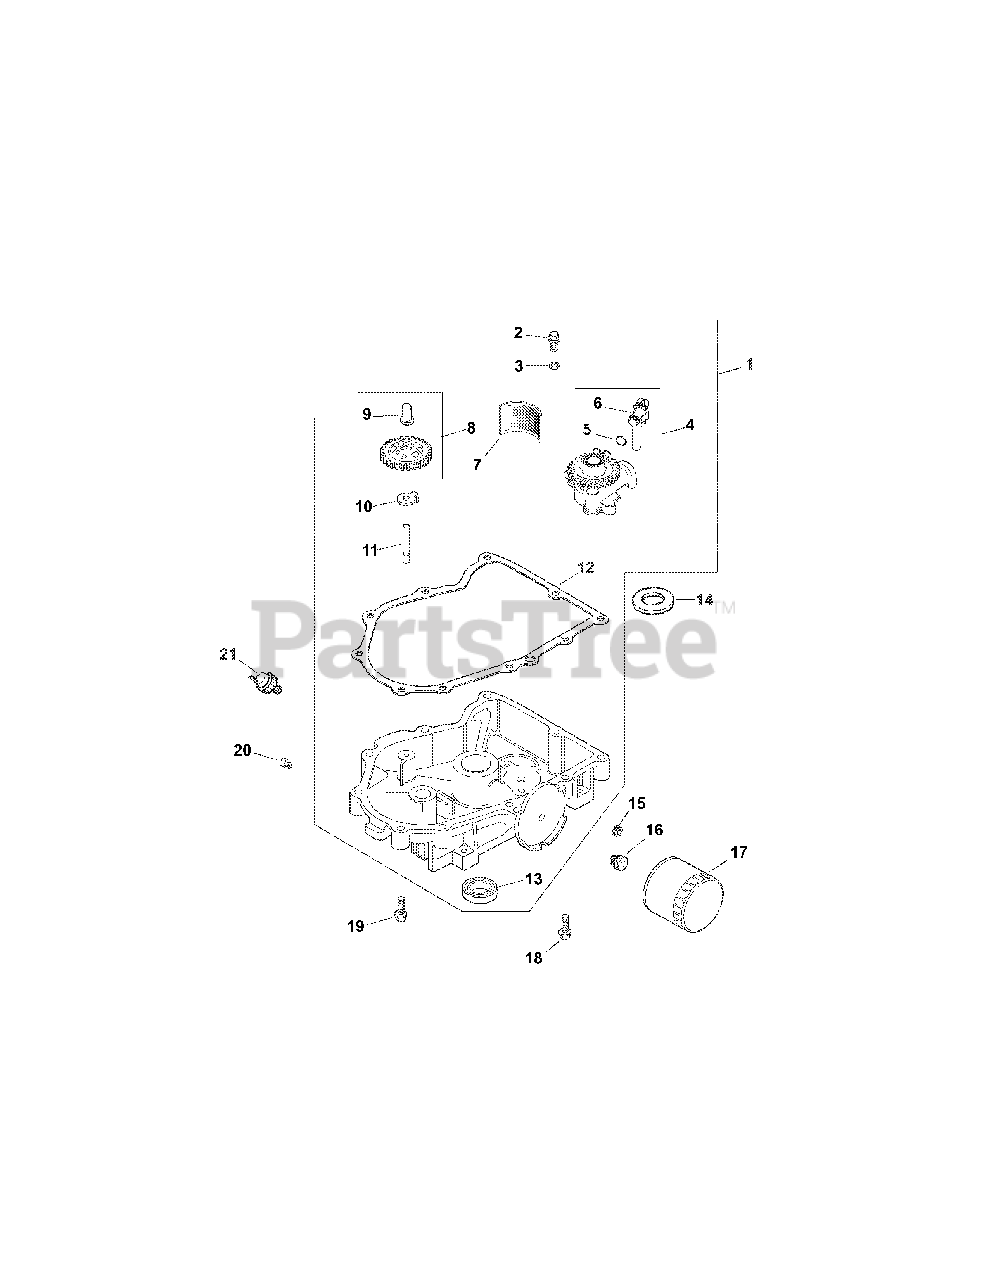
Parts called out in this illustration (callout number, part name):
1	Pan Assembly; oil (includes 2-13)
2	Screw, flg thd frm M6x1.0x25
3	Washer, flat 6 mm
4	Pump assembly, oil (Includes 5,6)
5	O-Ring, oil pickup
6	Tube, oil pickup
8	Kit, governor gear w/pin (Includes 9)
9	Pin, governor regulating
11	Shaft, governor gear
12	Gasket, oil pan (Select-A Seal)
13	Seal, oil (PTO end)
15	Plug, ctsk. 3/8 inch
16	Nipple, oil filter
17	Filter, oil
18	Screw, flg M8x1.25x45
19	Screw, flg M8x1.25x45
20	Plug, sq. hd. Pipe 3/8 inch
21	Switch, pressure
